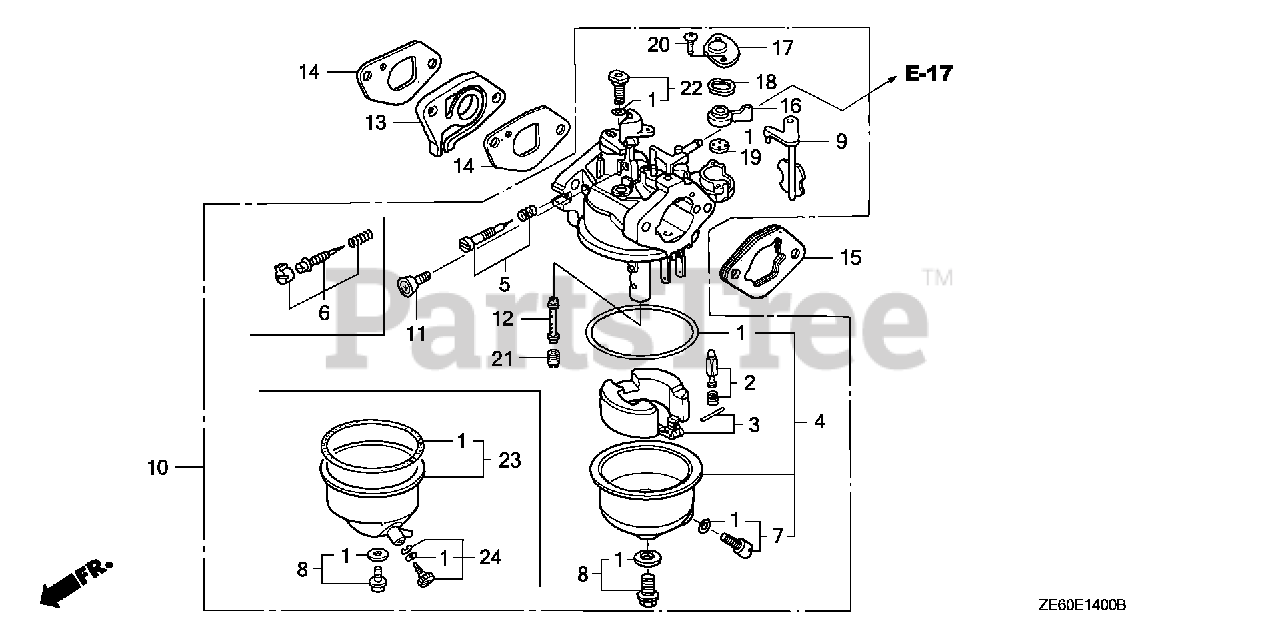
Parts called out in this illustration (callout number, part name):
1	GASKET SET (CARBURETOR NO.)
2	VALVE SET, FLOAT (SEAT NOT INCLUDED)
4	CHAMBER SET, FLOAT (CARBURETOR NO.)
5	SCREW SET, PILOT (CARBURETOR NO.)
7	SCREW SET, DRAIN (CARBURETOR NO.)
8	SCREW SET
9	CHOKE SET
10	CARBURETOR ASSY. (BE56A B)
11	SCREW, THROTTLE STOP
12	NOZZLE, MAIN (CARBURETOR NO.)
13	INSULATOR, CARBURETOR
14	GASKET, INSULATOR
15	SPACER, CARBURETOR
16	LEVER, PETCOCK (CARBURETOR NO.)
17	PLATE, LEVER SETTING (CARBURETOR NO.)
18	SPRING, PETCOCK LEVER (CARBURETOR NO.)
19	GASKET, PETCOCK (CARBURETOR NO.)
20	SCREW, PAN (3X6)
20	SCREW, PAN (3X8)
21	JET, MAIN (#52) Use from Engine SN BE03A H.
21	JET, MAIN (#55) Use from Engine SN BE03A H.
21	JET, MAIN (#58) (CARBURETOR NO.) (NOT AVAILABLE)
21	JET, MAIN (#60) Use up to Engine SN BE03A G.
21	JET, MAIN (#62) Use up to Engine SN BE03A G.
21	JET, MAIN (#65) (CARBURETOR NO.)
22	JET SET, PILOT (#35) (CARBURETOR NO.)
22	JET SET, PILOT (#38) (CARBURETOR NO.)
